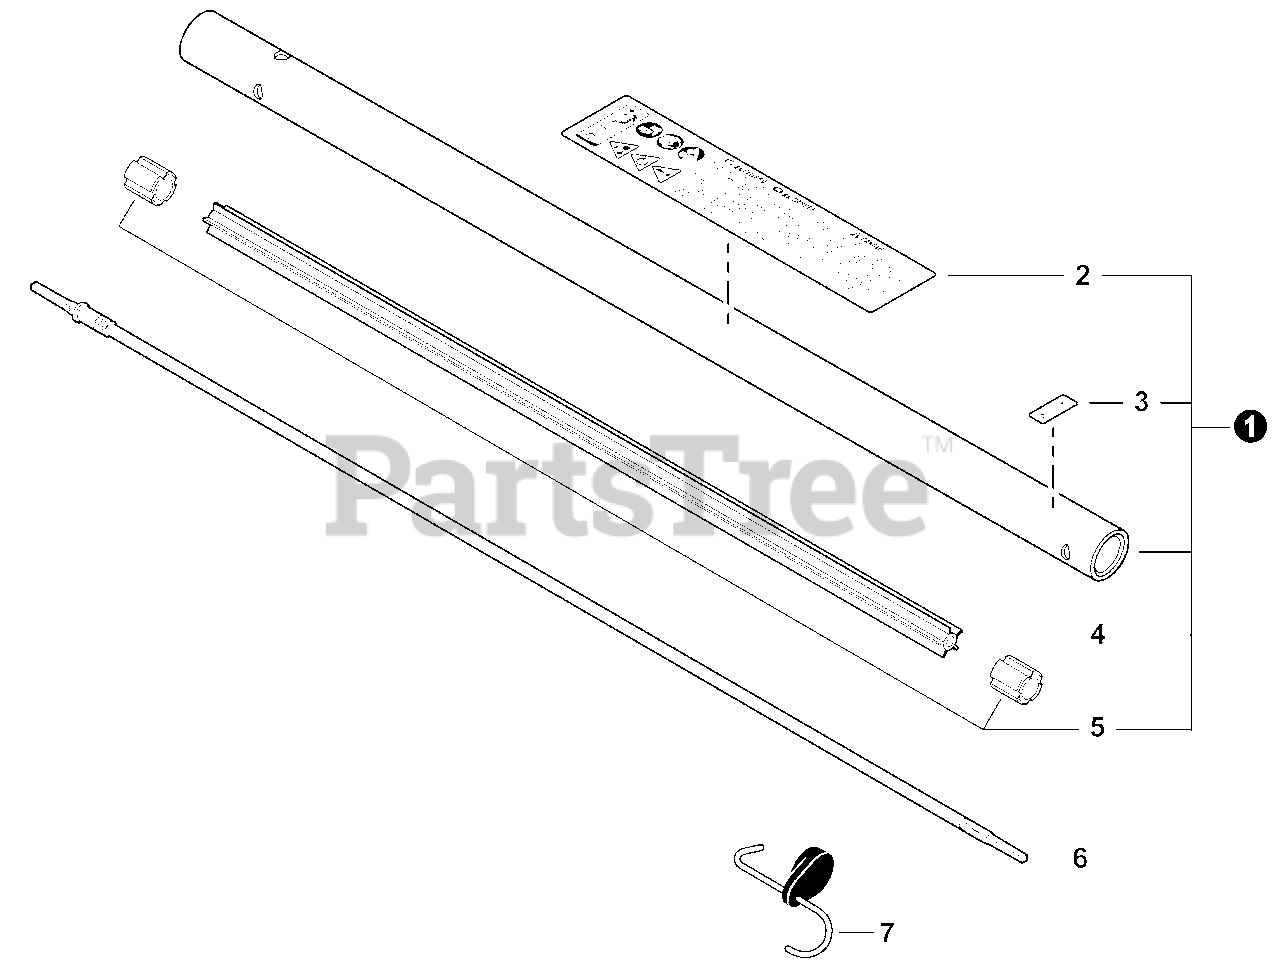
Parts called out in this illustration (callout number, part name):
1	MAIN PIPE ASSY
2	LABEL, CAUTION
3	LABEL - ALIGNMENT
4	LINER - FLEXIBLE
6	DRIVESHAFT - FLEXIBLE
7	HANGER, ATTACHMENT
